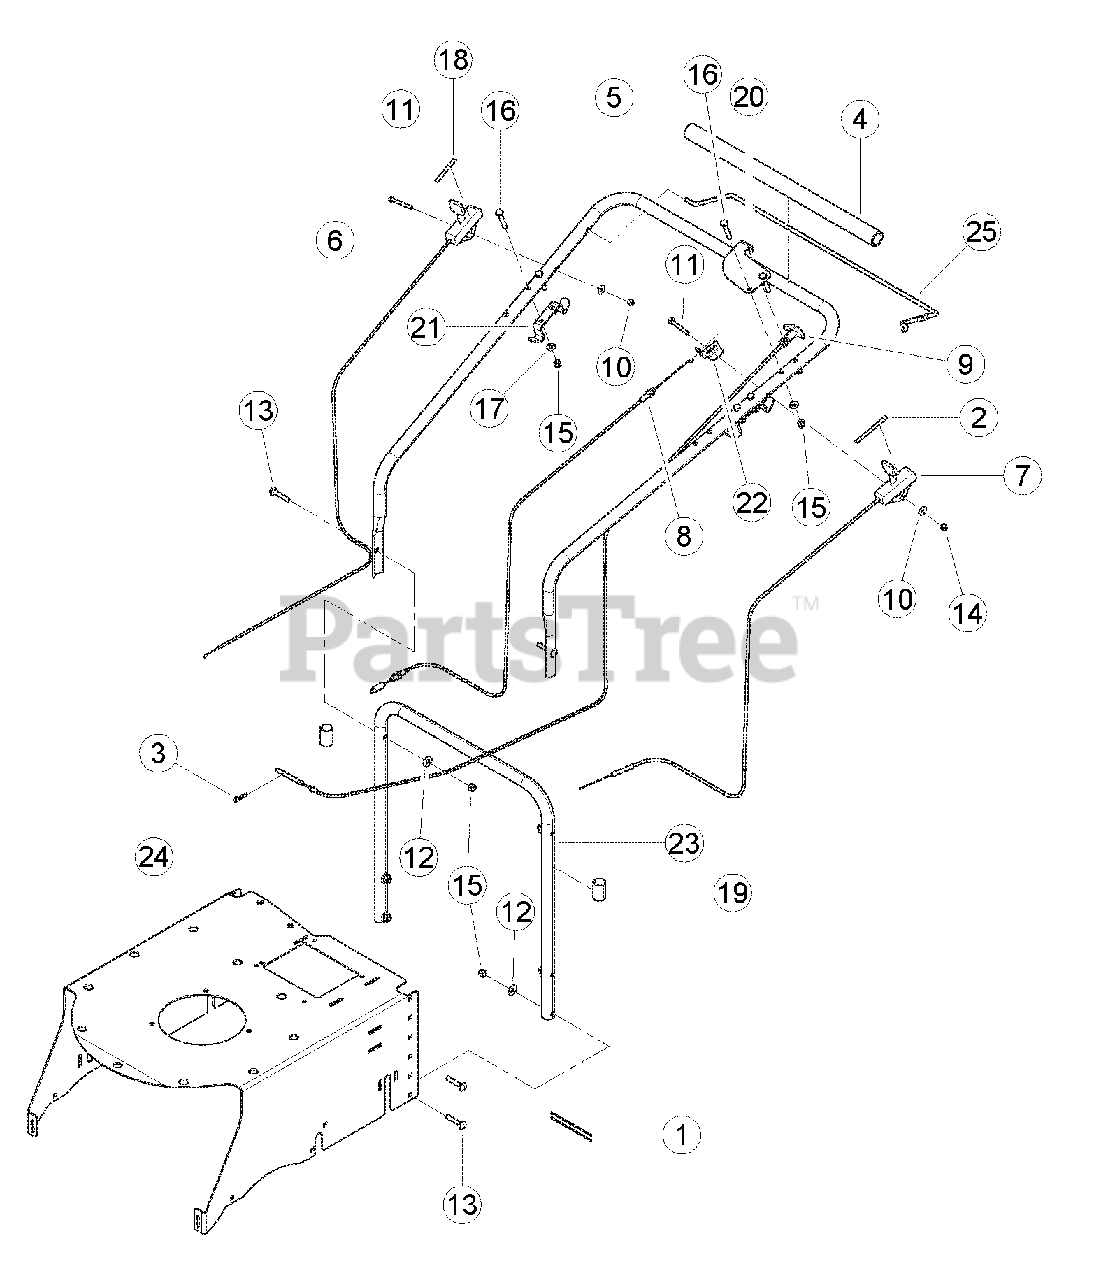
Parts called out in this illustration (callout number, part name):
1	STRAP, NYLON TIE
2	DECAL, 3 SPEED
3	CLIP, HAIRPIN ZP
4	PAD, FOAM HANDLEBAR
5	HANDLEBAR, BEARVAC UPPER
6	CONTROL, THROTTLE
7	CONTROL, TRANS. SHIFT
8	CONTROL, CLUTCH ENGAGEMENT
9	CONTROL, HEIGHT ADJUSTMENT
10	WASHER, 1/4 FLAT
11	BOLT, 1/4 X 2 HEX HD
12	WASHER, 5/16 FLAT
13	BOLT, 5/16 X 1-3/4 CRG GR5 ZP
14	NUT, 1/4 NYLOCK
15	NUT, 5/16 NYLOCK
16	BOLT, 5/16 X 1-3/4 HEX HD
17	WASHER, 5/16 SAE FLAT
18	DECAL, THROTTLE CONTROL
19	CAP, PLASTIC 7/8 IN
20	BRACKET, BEARVAC CABLE MOUNT
21	BRACKET, BAG HANGER
22	BRACKET, CLUTCH CABLE
23	HANDLEBAR, BEARVAC LOWER
24	SUPPORT, BEARVAC FRAME
25	BAIL, BEARVAC CLUTCH CONTROL
